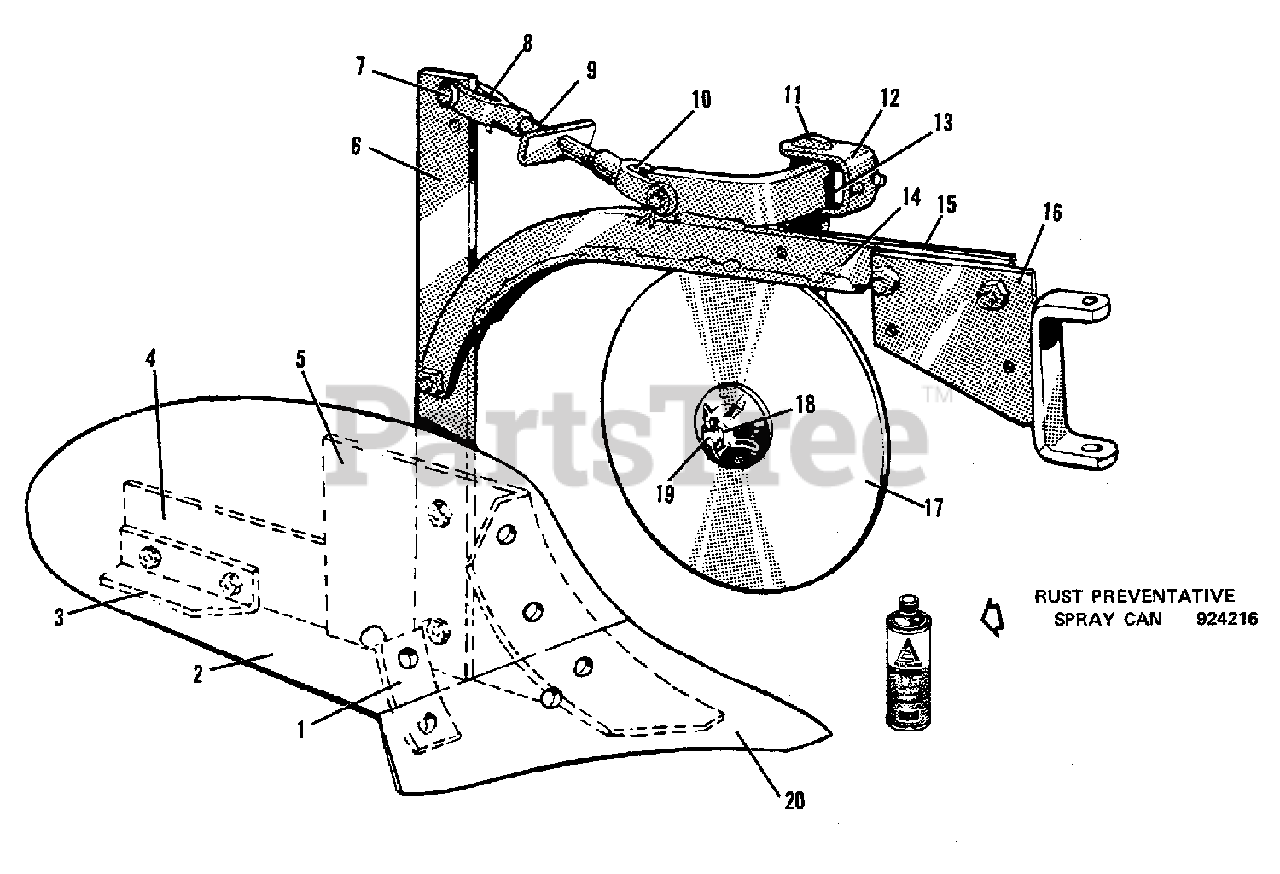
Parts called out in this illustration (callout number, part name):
1	BRACE, Moldboard
1	BOLT, Plow, 7/16 NC x 1-1/4
1	NUT, Square, 7/16 NC
2	MOLDBOARD
3	ANGLE, Slip Heel
3	BOLT, Plow, 7/16 NC x 1-1/4
3	NUT, Square, 7/16 NC
5	BOLT, Plow, 7/16 NC x 1-1/4
5	NUT, Square, 7/16 NC
6	BOLT, Plow, 1/2 NC x 1-1/2
6	NUT, 1/2 NC
6	LOCKWASHER, 1/2
7	PIN, Yoke
7	PIN, Cotter, 1/8 x 1
8	YOKE, Rod, L.H.
8	NUT, 5/8 NC
9	ROD ASSEMBLY, Yoke
10	YOKE, Rod, R.H.
11	STANDARD, Coulter
12	CLAMP, Coulter Standard
13	NUT, Special
14	BEAM ASSEMBLY, Plow
14	CAPSCREW, 1/2 NC x 1-3/4
14	NUT, 1/2 NC
14	BOLT, 3/8 NC x 2-1/4
14	NUT, 3/8 NC
14	LOCKWASHER, 3/8
15	SPACER, Plow Beam
16	END ASSEMBLY, Plow Beam
17	COULTER ASSEMBLY, (Including BUSHING)
17	PIN, Cotter, 1/8 x 1
17	FITTING, Lube, 1/4
18	WASHER, Coulter
19	SPINDLE, Wheel
20	SHARE, Plow
